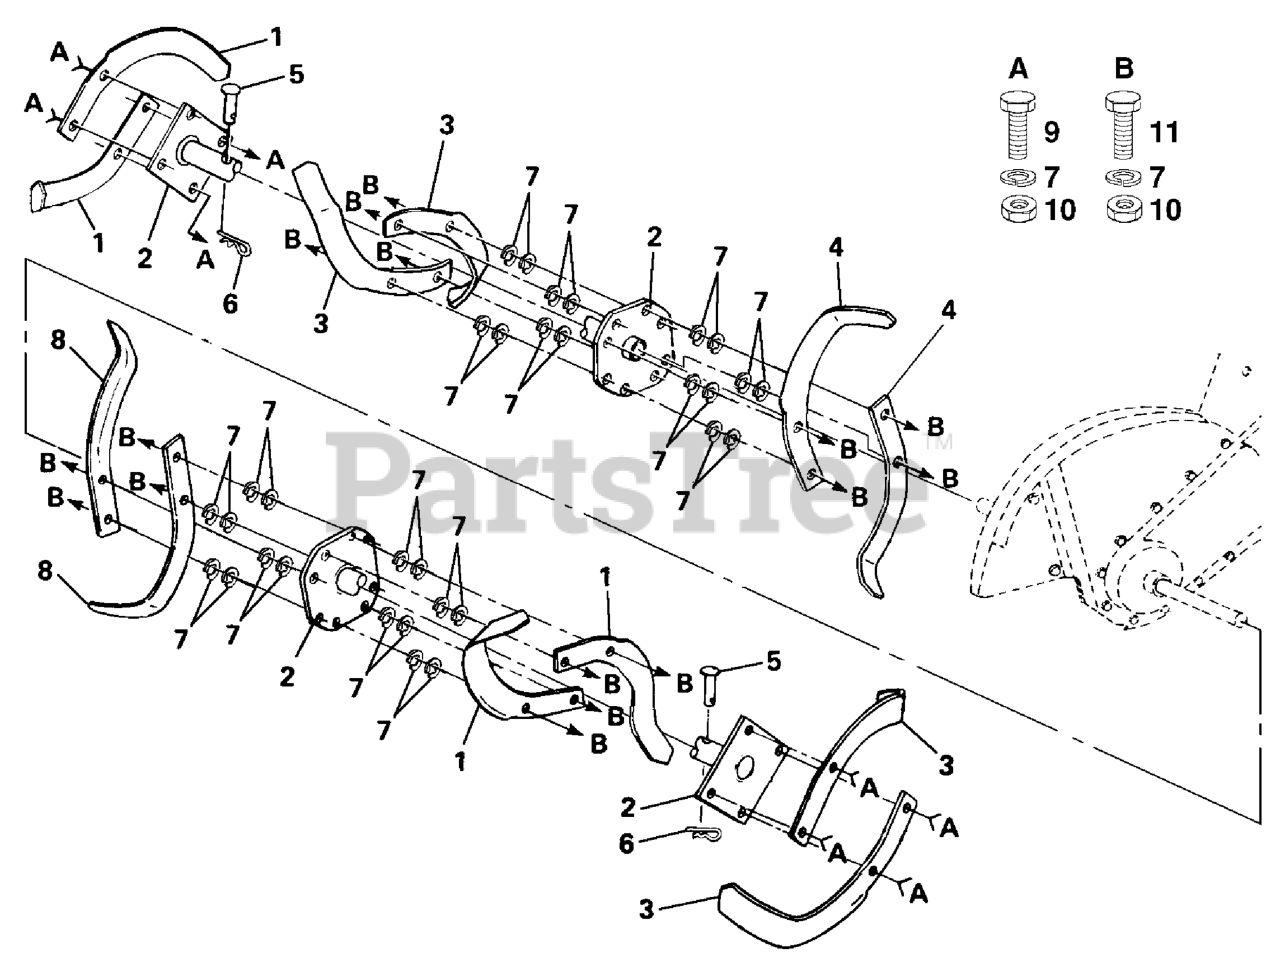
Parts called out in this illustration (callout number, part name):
1	TINE, LH 14"
2	DNO HUB ASMBLY
3	TINE, RH 14"
4	TINE.LH.14".CRT
6	SPRING RETAINER
7	WASHER, LOCK 3/8
8	TINE.RH.14".CRT
9	BOLT.HEX.001X20.37-24X1.ZINC
10	NUT
11	BOLT.3/8-24X1-1/2
